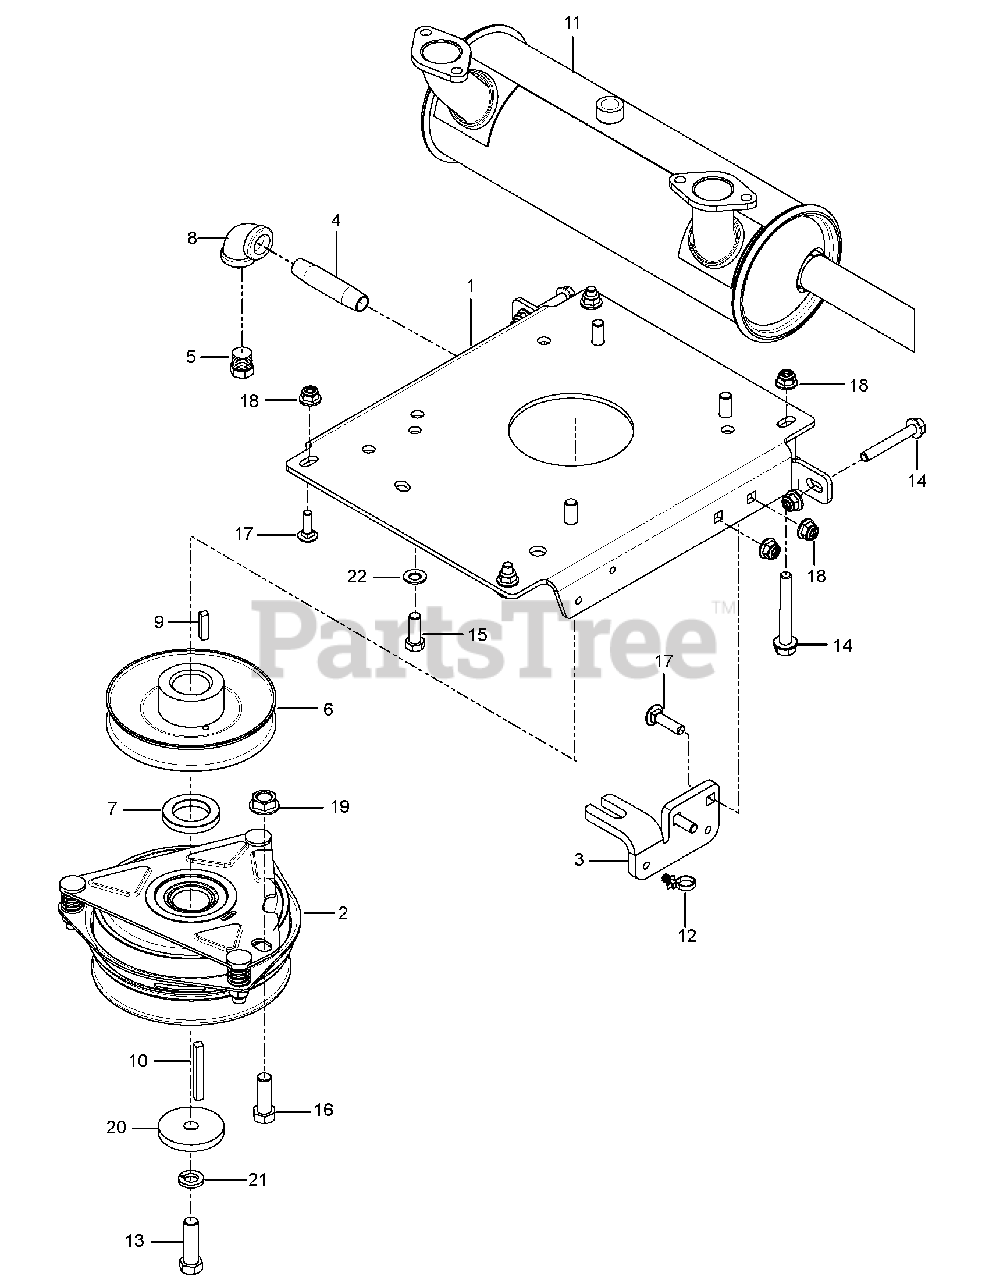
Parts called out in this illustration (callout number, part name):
1	PLATE.PNT.ENGINE.PZ/PZT.EDIP
2	CLUTCH, 150 FT/LBS
3	STOP, CLUTCH, OGURA
4	PIPE NIPPLE 3/8 X 3
5	PLUG, DRAIN 3/8 NPTF
6	PULLEY, ENGINE
7	SPACER, .25 X 1.135 I.D.
8	90 DEG.ELBOW 3/8NPT
9	KEY 1/4 SQ X 1.0
10	KEY 1/4 SQ X 2
11	MUFFLER.KOH.EFI.824CC
12	TIE WRAP, 8-3/8", W/CLIP
13	CLUTCH BOLT7/16-20X1.5GR5.96HR
14	HHFS 5/16-18 X 2.25 GD 5
15	HCS 3/8-16X1.GRD.5.ZD
16	HCS 7/16-14 X 1-1/4 GR 5 ZD
17	RHSNB 5/16C X 1
18	5/16-18 NYLOC FLANGE NUT
19	NUT 7/16C WHIZ
20	BLADE WASHER
21	WASHER 7/16 LOCK
22	WASHER, 3/8 DISC SPRING SPEC
